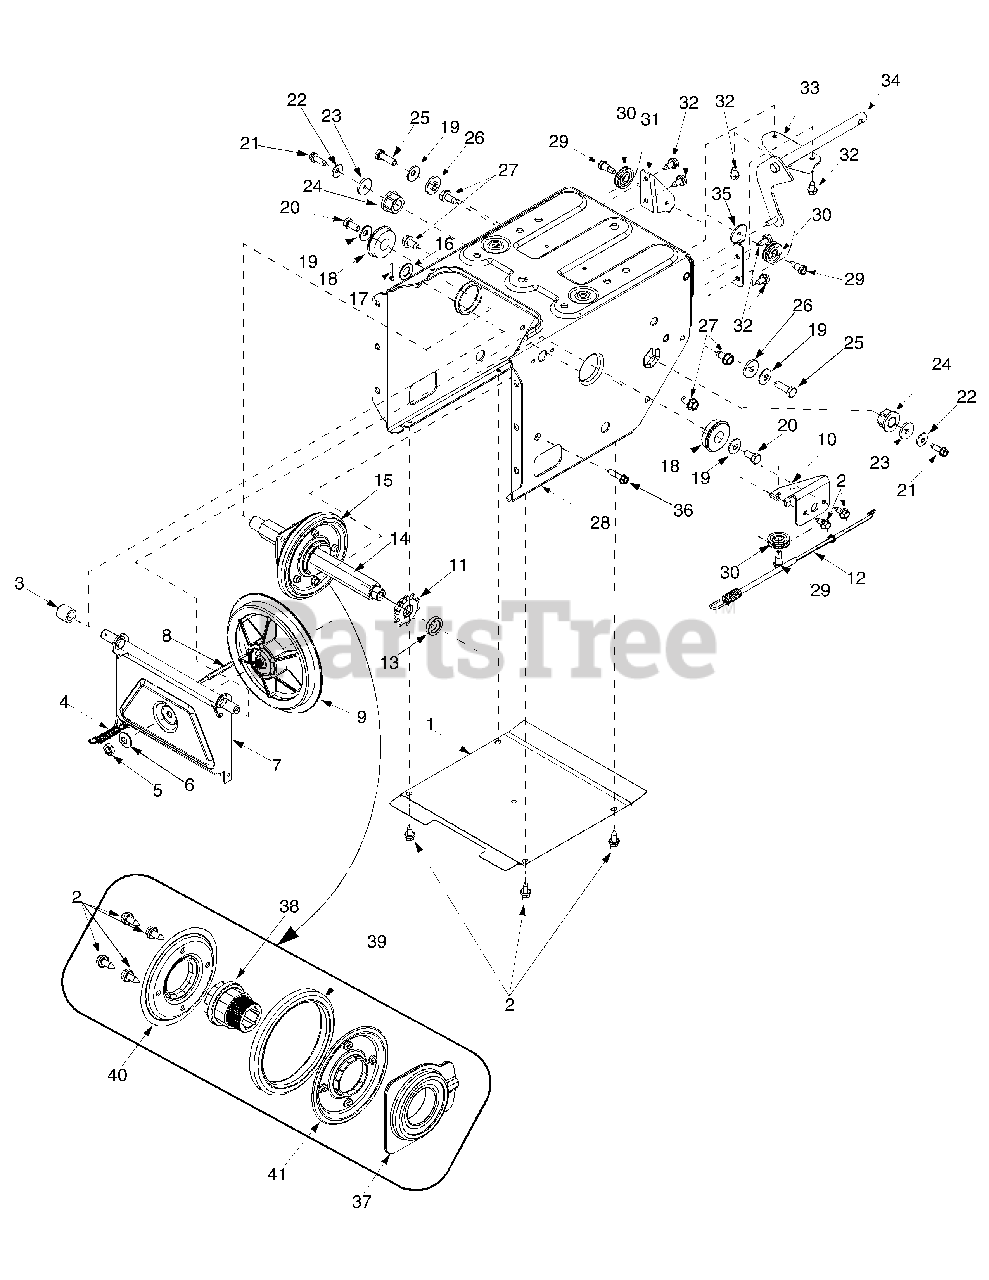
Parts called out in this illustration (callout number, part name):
3	Spacer
4	Extension Spring
5	Jam Nut 3/8-24
6	Bell Washer
9	Friction Disc
12	Auger Cable
13	Spacer
14	Hex Track Drive Shaft
15	Friction Wheel Assembly
16	Flat Washer
17	Cotter Pin
18	Ball Bearing
19	Bell Washer
20	Hex Cap Screw 5/16-18 x.625
21	Tap Screw 1/4-20 x.75
22	Bell Washer.265 ID x.75 OD
23	Flat Washer 1/4 ID x.93 OD
24	Hex Flange Bearing
25	Hex Cap Screw 5/16-18 x 1"
26	Shoulder Spacer
27	Tap Screw 5/16-18 x.625
29	Hex Screw 1/4-28 x.375
30	Cable Roller
37	Friction Wheel Bearing Ass’y
38	Friction Wheel Hub
39	Friction Wheel Rubber
40	Friction Plate
41	Friction Plate
